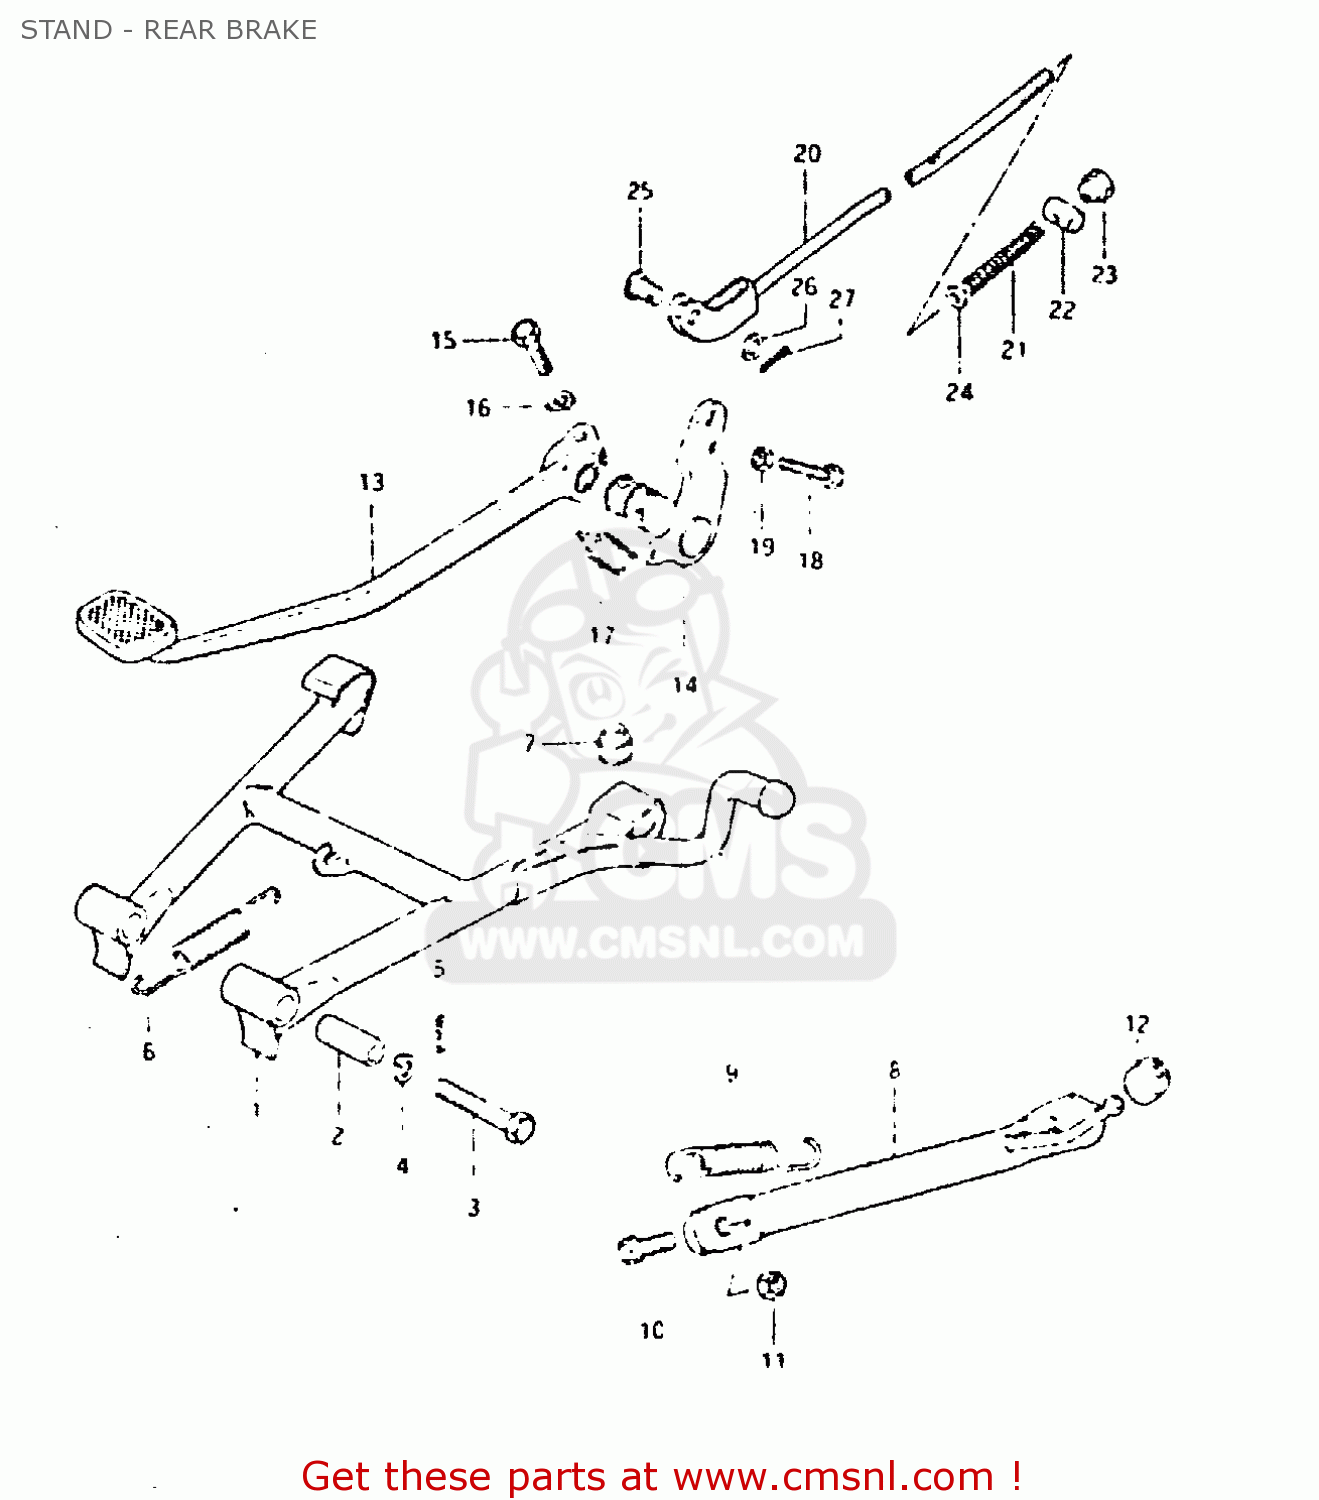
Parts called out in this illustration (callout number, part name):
1	STAND,CENTER
2	SPACER(10X16X38.8)
3	BOLT
4	LOCK WASHER
5	CLIP
6	SPRING
7	CUSHION
8	STAND,SIDE
9	SPRING
10	BOLT(10X30)
11	NUT
12	CUSHION
13	PEDAL,BRAKE
14	ARM,BRAKE PEDAL ROD
15	BOLT
16	LOCK WASHER
17	SPRING
18	BOLT
19	NUT
20	ROD ASSEMBLY,REAR BRAKE
21	SPRING
22	PIN
23	NUT
24	WASHER
25	PIN(L:13.5)
26	WASHER
27	PIN 20X20
